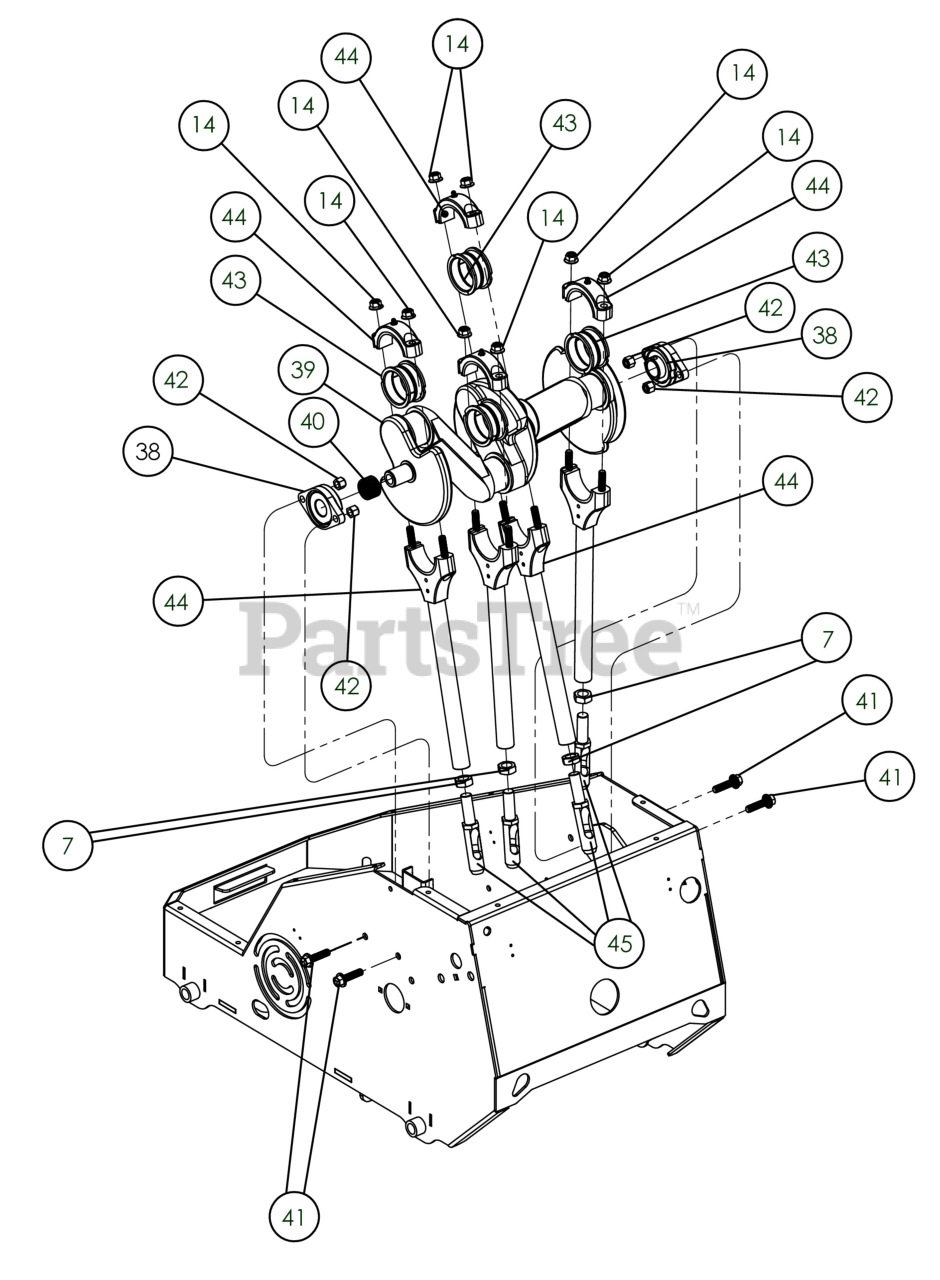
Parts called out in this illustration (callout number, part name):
7	NUT JAM, 5/8-11 ZP
14	NUT-HEX-NYLK, FLG .375"-16 ZP
38	CARTRIDGE BEARING
39	CRANKSHAFT (PL410)
40	SPRING, WAVE 1.000" X .700"
41	SCR-CAP, HSWH .375"-16 X 1.500" G5 ZP
42	NUT LOCK 3/8"-16 HEX
43	BEARING JOURNAL 2" DIA
44	ASM, TINE ROD AND CAP
45	TINE, PLUGR .625"-11 BLACK
